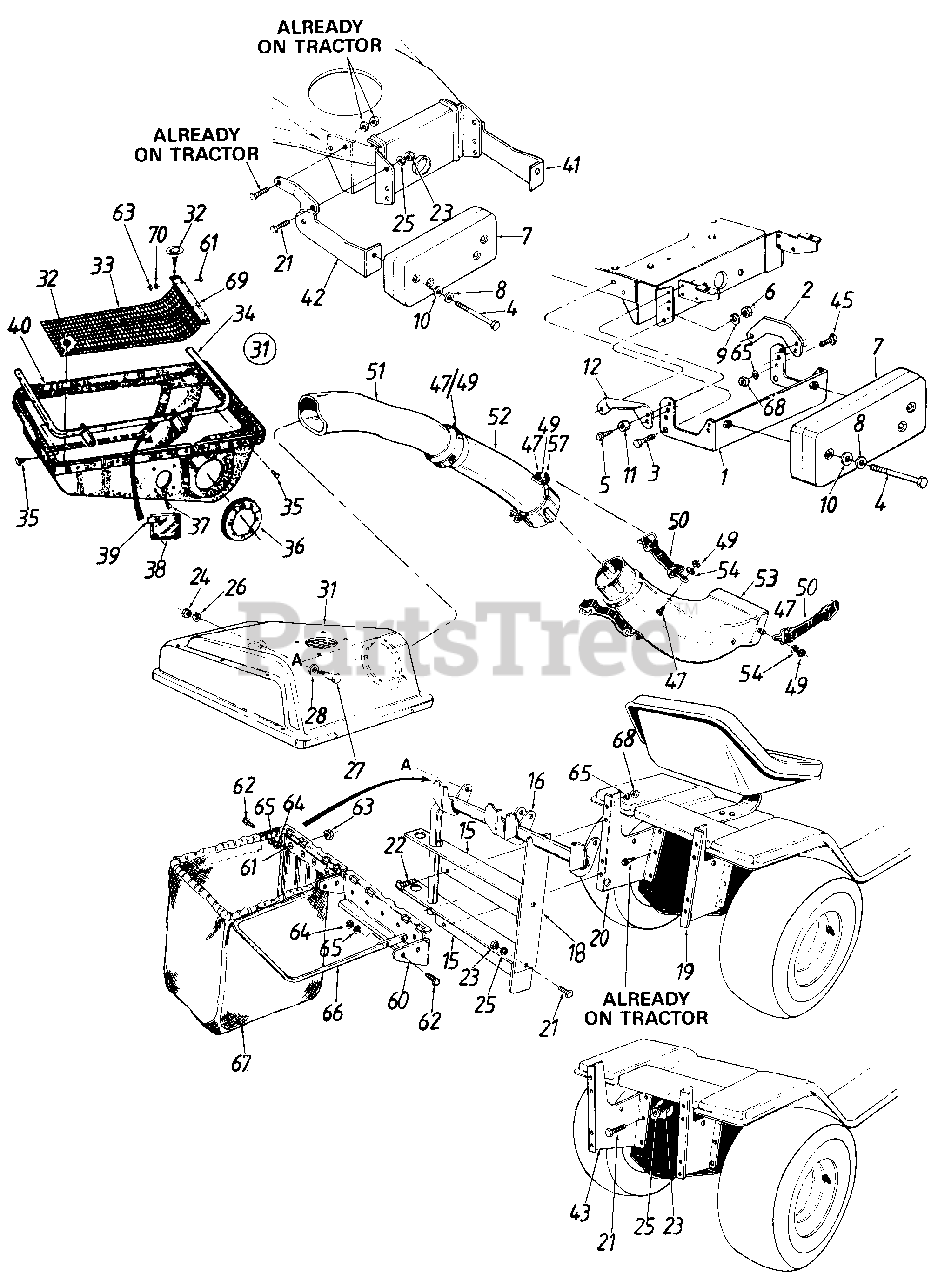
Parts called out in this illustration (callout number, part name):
1	Weight Brkt. Ass'y.
2	Weight Brkt. Tie Strap - L.H.
3	Hex Bolt 7/16-20 x 1.0" Lg.*
4	Hex Bolt 3/8-16 x 4.5" Lg.*
5	Hex AB Tap Scr. 5/16-18 x 1.0"
6	Hex Jam Nut 7/16-20 Thd.
7	Front Counter Weight 38 lbs.
8	Bell.-Wash. 400" I.D. x .88" O.D.
9	L.-Wash. 7/16" I.D.
10	Fl.-Wash. .390" I.D. x 1.12" O.D.
11	Spacer
12	Weight Brkt. Tie Strap-R.H.
15	Catcher Support Tube Mtg. Brkt
16	Catcher Support Tube Ass'y.
18	Catcher Latch and Support Brkt.
19	Grass Catcher Support Brkt- R.H.
20	Grass Catcher Support Brkt. - LH.
21	Hex Bolt 5/16-18 x .75" Lg.*
22	Hex Bolt 1/4-20 x .62" Lg. - Grade 5
23	Hex Nut 5/16-18 Thd.*
24	Hex Nut 3/8-16 Thd.*
25	L.-Wash. 5/16" I.D.*
26	L.-Wash. 3/8" I.D.*
27	Shld. Bolt 3/8-16 x .500" Dia.
28	Bell.-Wash. .505" I.D. x 1.00" O.D.
31	Grass Catcher Cover Ass'y.
32	Twist Fastener
33	Screen
35	Hex Tap Scr. 1/4-20 x .5" Lg.
36	Seal
37	Truss Mach. B-Tap Scr. #10 x .5" Lg.
38	Plastic Plate
39	Speed Nut
40	Grass Catcher Cover
41	Weight Brkt. Ass'y. -L.H.
42	Weight Brkt. Ass'y. R.H.
43	Grass Catcher Support Brkt.
45	Hex Bolt 1/4-20 x .88" Lg.
47	Hex Bolt 1/4-20 x .50" Lg.*
49	Hex Ins. L.-Nut 1/4-20 Thd.
50	Retainer Strap Ass'y.
51	Catcher Elbow
52	Catcher Tube
53	Discharge Chute
54	L.-Wash. .270" I.D. x .57" O.D.
57	Retainer Hook Brkt.
61	Truss Mach. Scr. #10-24 x .50" Lg.
62	Hex Bolt 1/4-28 x .75" Lg.
63	Hex Sems Nut #10-24 Thd.
64	Hex Nut 1/4-28 Thd.*
65	L.-Wash. 1/4" I.D.*
67	Grass Catcher Bag
68	Hex Nut 1/4-20 Thd.*
69	Screen Mtg. Brkt.
70	Flat Wash. 1/4" I.D.
